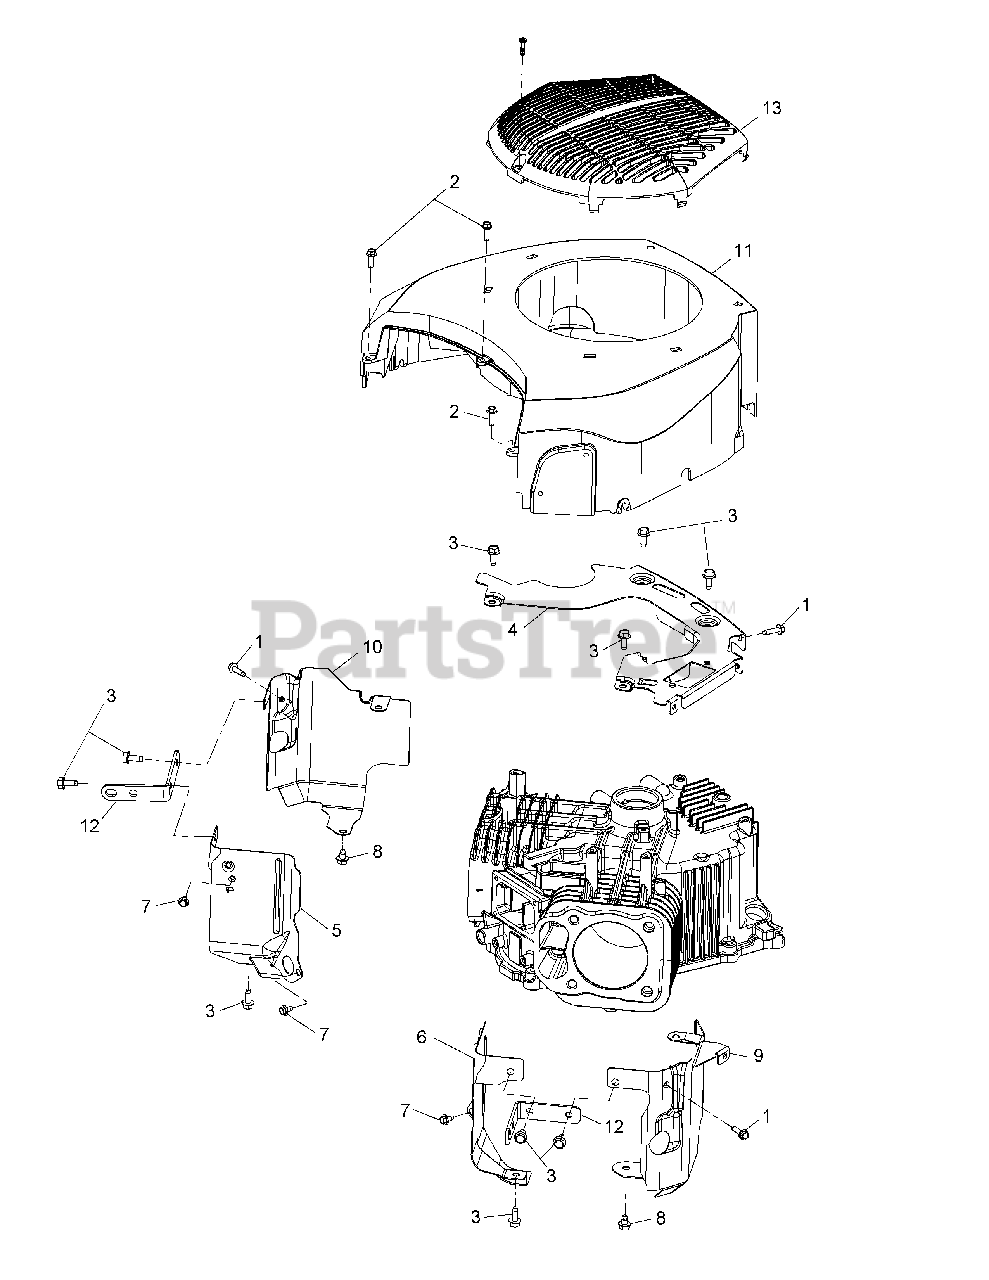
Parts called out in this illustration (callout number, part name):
1	Thread Forming Screw
3	Thread Forming Screw
4	Backing Plate
5	Valley Baffle, #1 Cylinder
6	Valley Baffle, #2 Cylinder
7	Thread Forming Screw
8	Thread Forming Screw
9	Left Barrel Baffle
10	Right Barrel Baffle
11	Blower Housing
